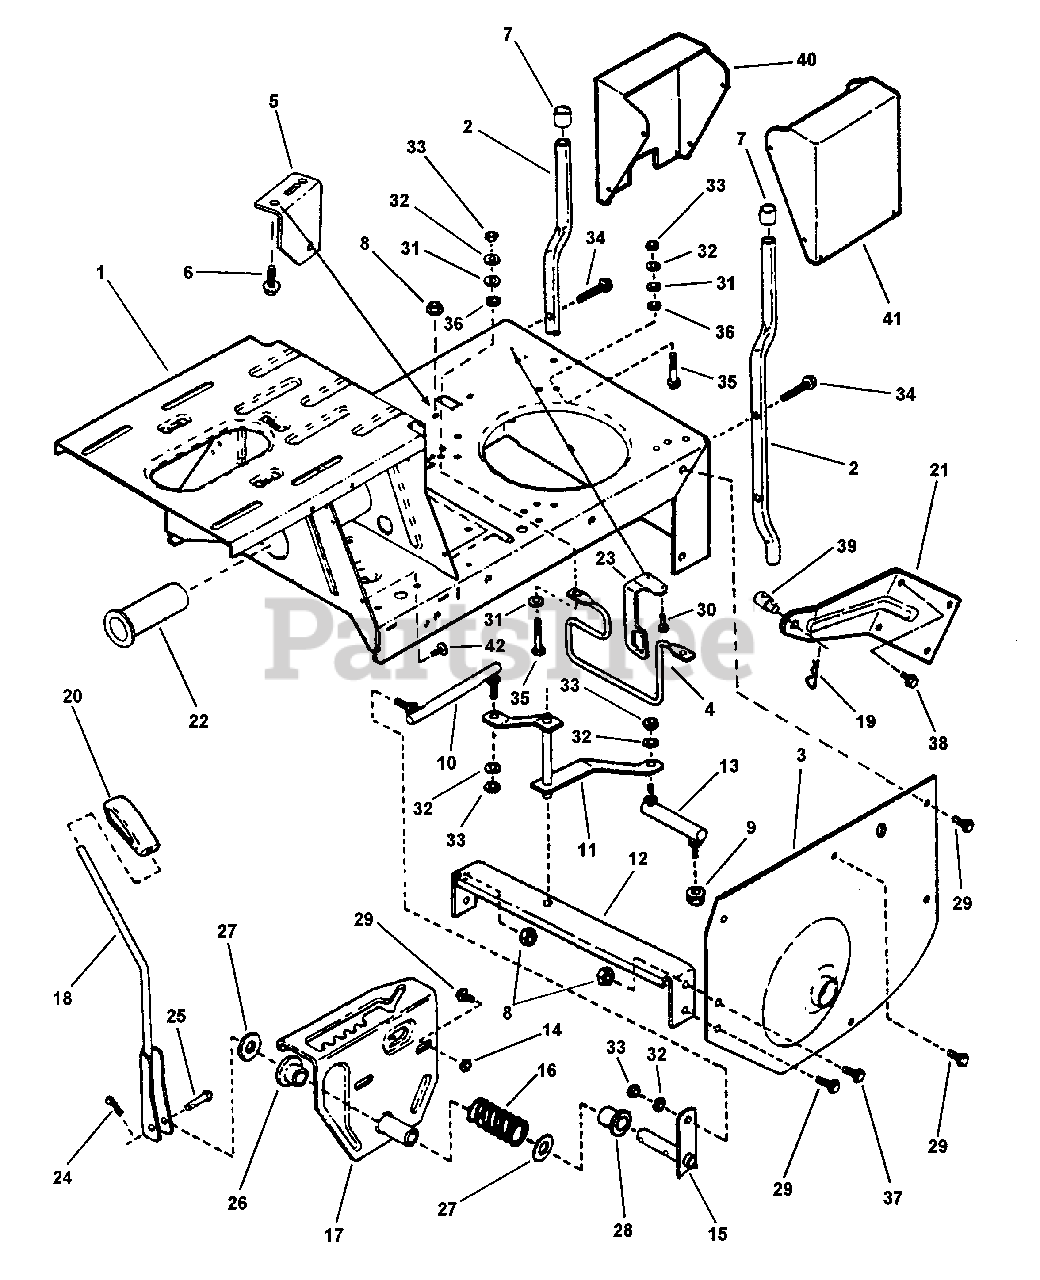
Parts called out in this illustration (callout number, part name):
1	CASE, Main (Standard)
2	BUMPER, Rear
3	FENDER, Left Hand
4	GUIDE, Belt
5	BRACKET, Drive Support
6	BOLT, 5/16-18 X 3/4" Hex Flange Lock
7	CAP, Bumper
8	NUT, 5/16-18 Hex Flange Lock
9	NUT, 5/16-24 Hex Flange Lock
10	LINK, Shift (Long)
11	ARM, Shift
12	BRACE, Cross
13	LINK, Shift (Short)
14	NUT, 5/16-18 Hex
15	ARM, Shift Handle
16	SPRING, Shift Handle
17	DETENT, Shift
18	HANDLE, Shift
19	HAIRPIN, 3/32 X 1-1/2"
20	GRIP, Shift Handle
21	WING, Rear
22	BUSHING, Pilot
23	BRACKET, Switch
24	PIN, 3/32 x 3/4" Cotter
25	PIN, 1/4 x 1-3/4" Tapered Clevis
26	BUSHING, Nylon
27	WASHER, Thrust
28	BUSHING, Nylon
29	SCREW, 5/16-18 x 5/8" Self-Tap
30	SCREW, 10-32 x 1/4" Hex Washer Self-Tap
31	WASHER, 5/16" Flat
32	WASHER, 5/16" Split Lock
33	NUT, 5/16-24 Hex
34	SCREW, 5/16-18 x 1-1/2" Self-Tap
35	SCREW, 5/16-24 x 1-1/2" Hex Head Cap
36	RETAINER, 5/16 Bolt
37	SCREW, 5/16-18 x 3/4" Hex Head Cap
38	SCREW, 5/16-18 X 3/4" Hex Self-Tap
39	SWIVEL
40	COVER, Switch
41	COVER, Battery
42	FASTENER, 1/4 x 3/4" Ratchet
